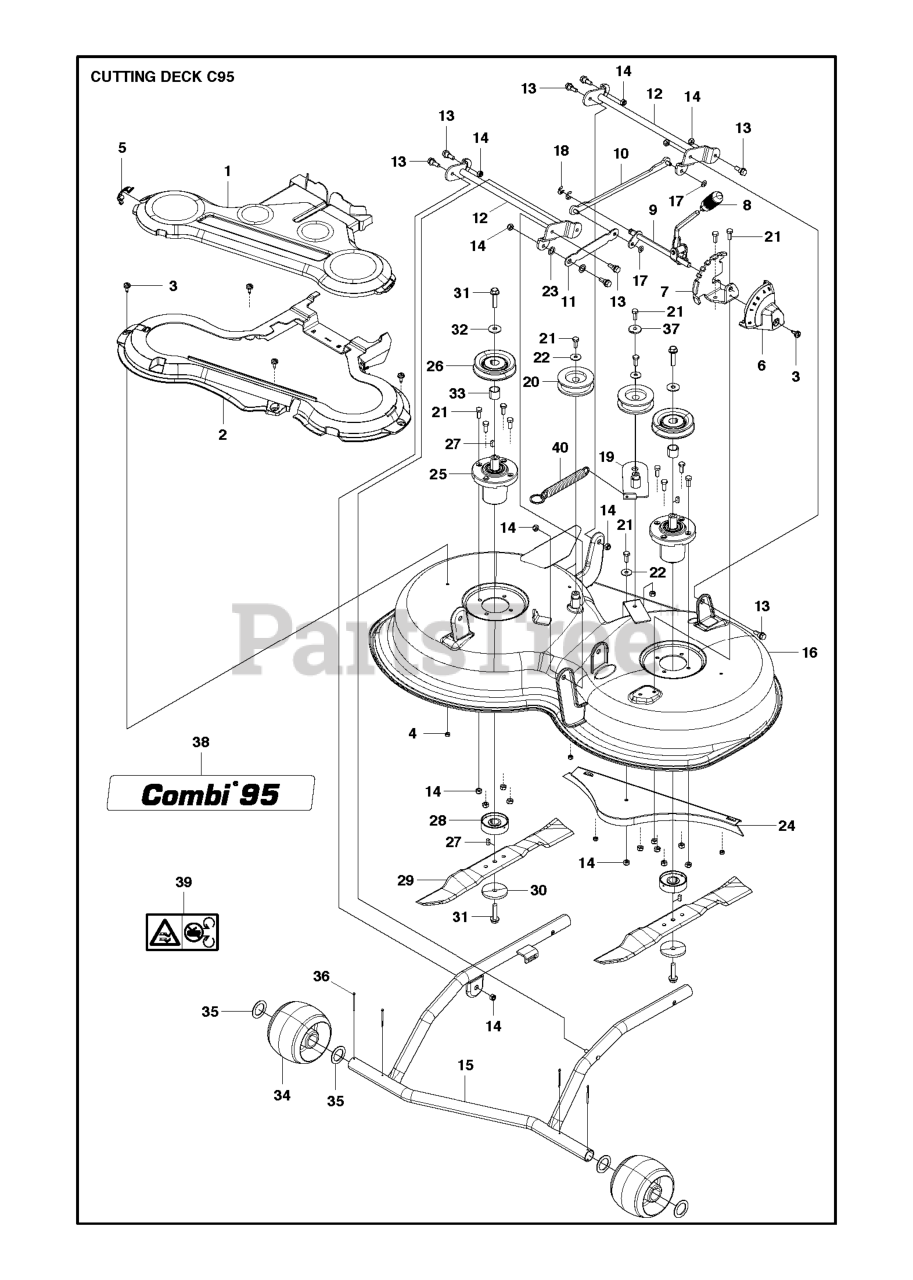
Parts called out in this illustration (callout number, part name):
4	LOCKNUT M6
5	BUCKLE ORANGE
14	LOCKNUT M8
18	RETAINING RING
20	PULLEY
21	SCREW
36	COTTER PIN
37	WASHER
